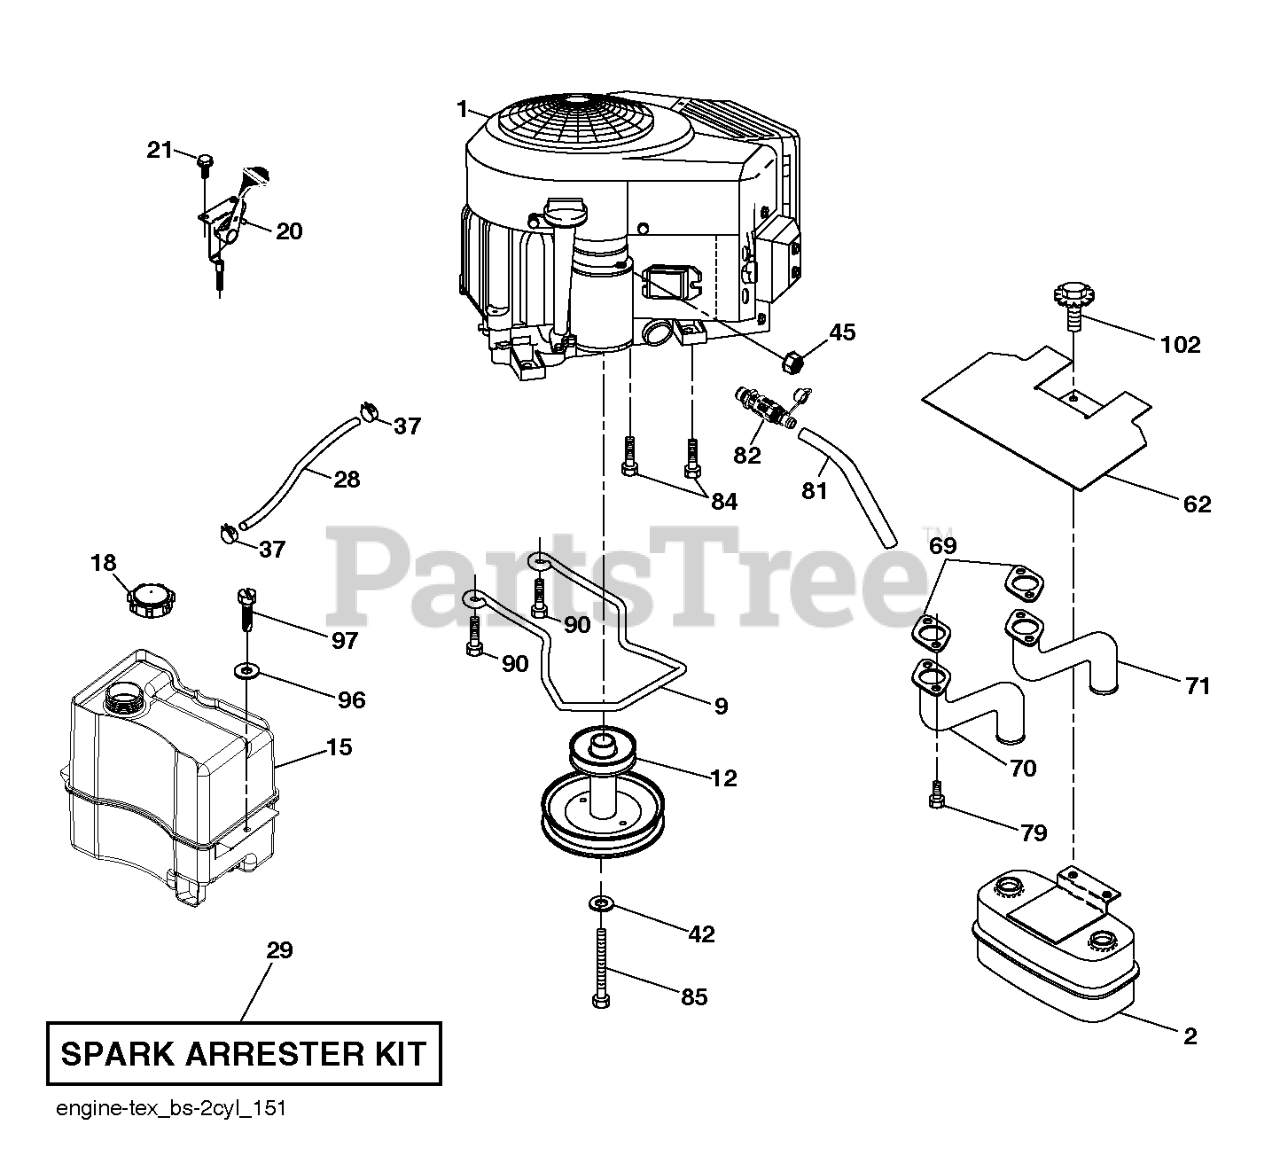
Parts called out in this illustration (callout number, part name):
2	MUFFLER.ASM.TWIN.MNTG.BRACKET
9	KEEPER.BELT.ENG.3.25"2BOLT.PNT
12	PULLEY.ENGINE.5.0.PD
15	TANK.ASSEMBL.2.5GAL.NON-EPA
18	CAP ASM.FUEL.2.25"FR.
20	CONTROL.TH/CK.COBRA.B&S.TWN.
21	SCREW.#10 X 0.750.BOS (2 2)
28	LINE.FUEL.20"FRONT.EMI
29	Arrester, Spark (Optional equipment) (AYP part number)
37	Clamp Hose Black (AYP part number)
42	WASHER 7/16 LOCK
45	Nut Keps Hex 1/4 - 20 UNC (AYP part number)
62	SHIELD.HEAT.MUFFLER
69	GASKET.MUFFLER
70	EXHAUST.TUBE.LH.BS/TWIN
71	EXHAUST.TUBE.RH.B&S.TWIN.INTEK
79	SCREW.SOCKET.HEAD.5/16-18
81	TUBE, DRAIN OIL ASM.
82	VALUE.OIL.DRAIN
84	SCREW.3/8-16
85	Speed Clip
90	SCREW 3/8-16X1
96	Washer 9/32 x 7/8 x 16 Gauge (AYP part number)
97	SCREW HEXWSHR 1/4-20X3/4
102	SCREW
